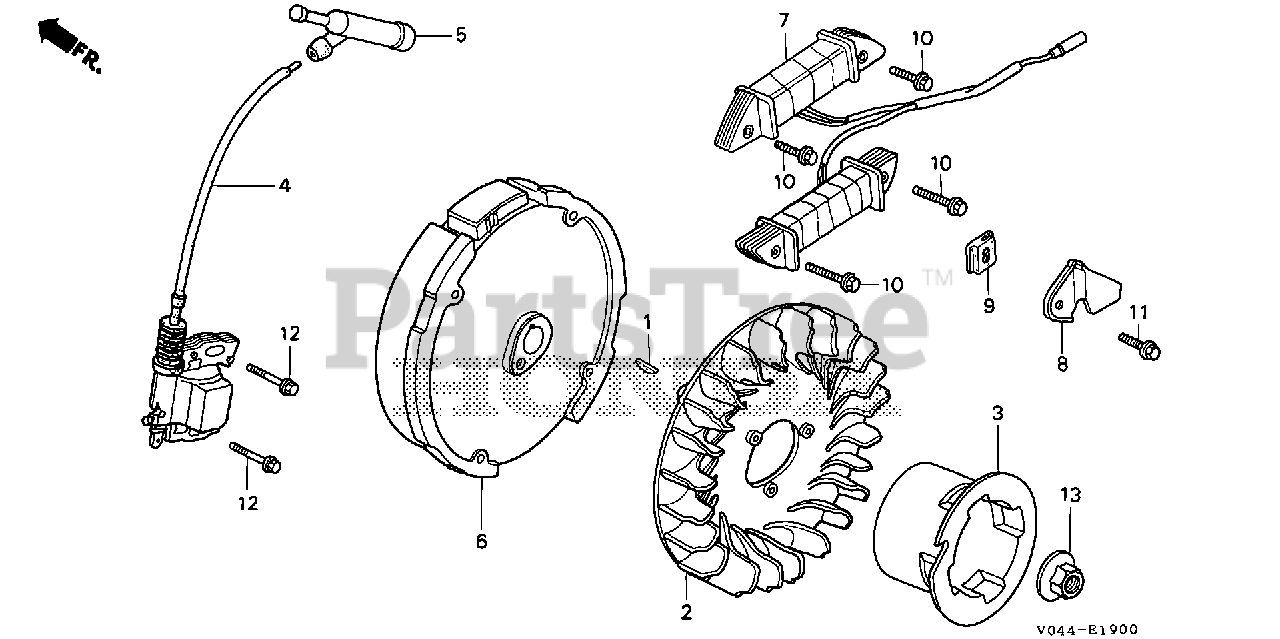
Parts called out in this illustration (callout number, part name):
1	KEY, SPECIAL WOODRUFF (25X18)
2	FAN, COOLING
3	PULLEY, STARTER
4	COIL ASSY., IGNITION
5	CAP ASSY., NOISE SUPPRESSOR (NICHIWA Y-EZ RTFM256)
6	FLYWHEEL (LAMP)
7	COIL ASSY., LAMP (12V/50W)
8	CLAMP, WIRE
9	GROMMET, WIRE
10	BOLT, FLANGE (6X28) (CT200)
11	BOLT, FLANGE (5X10)
12	BOLT, FLANGE (6X25) (CT200)
13	NUT, SPECIAL (14MM)
